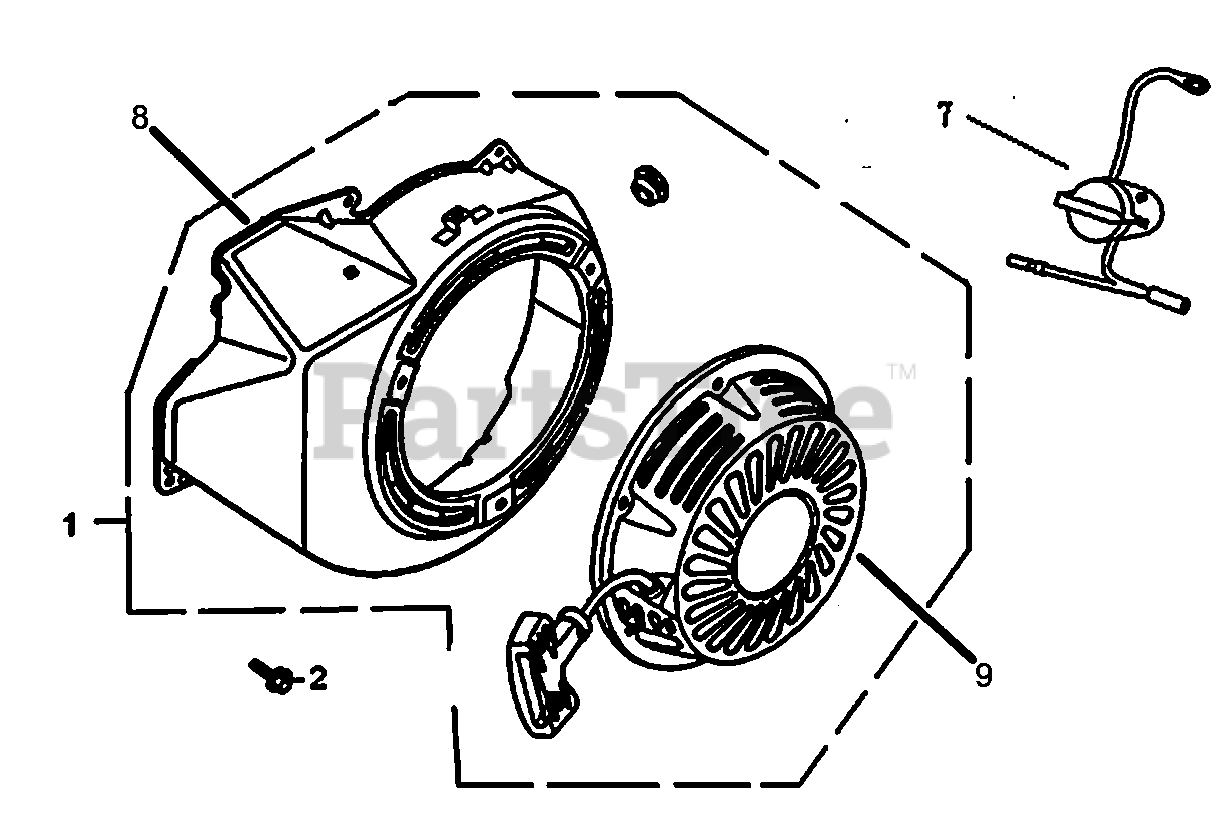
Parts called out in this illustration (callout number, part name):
1	STARTER ASSY.
2	BOLT, FLANGE
7	ENGINE SWITCH
8	BLOWER HOUSING, RECOIL STARTER
9	ASSY, RECOIL STARTER
